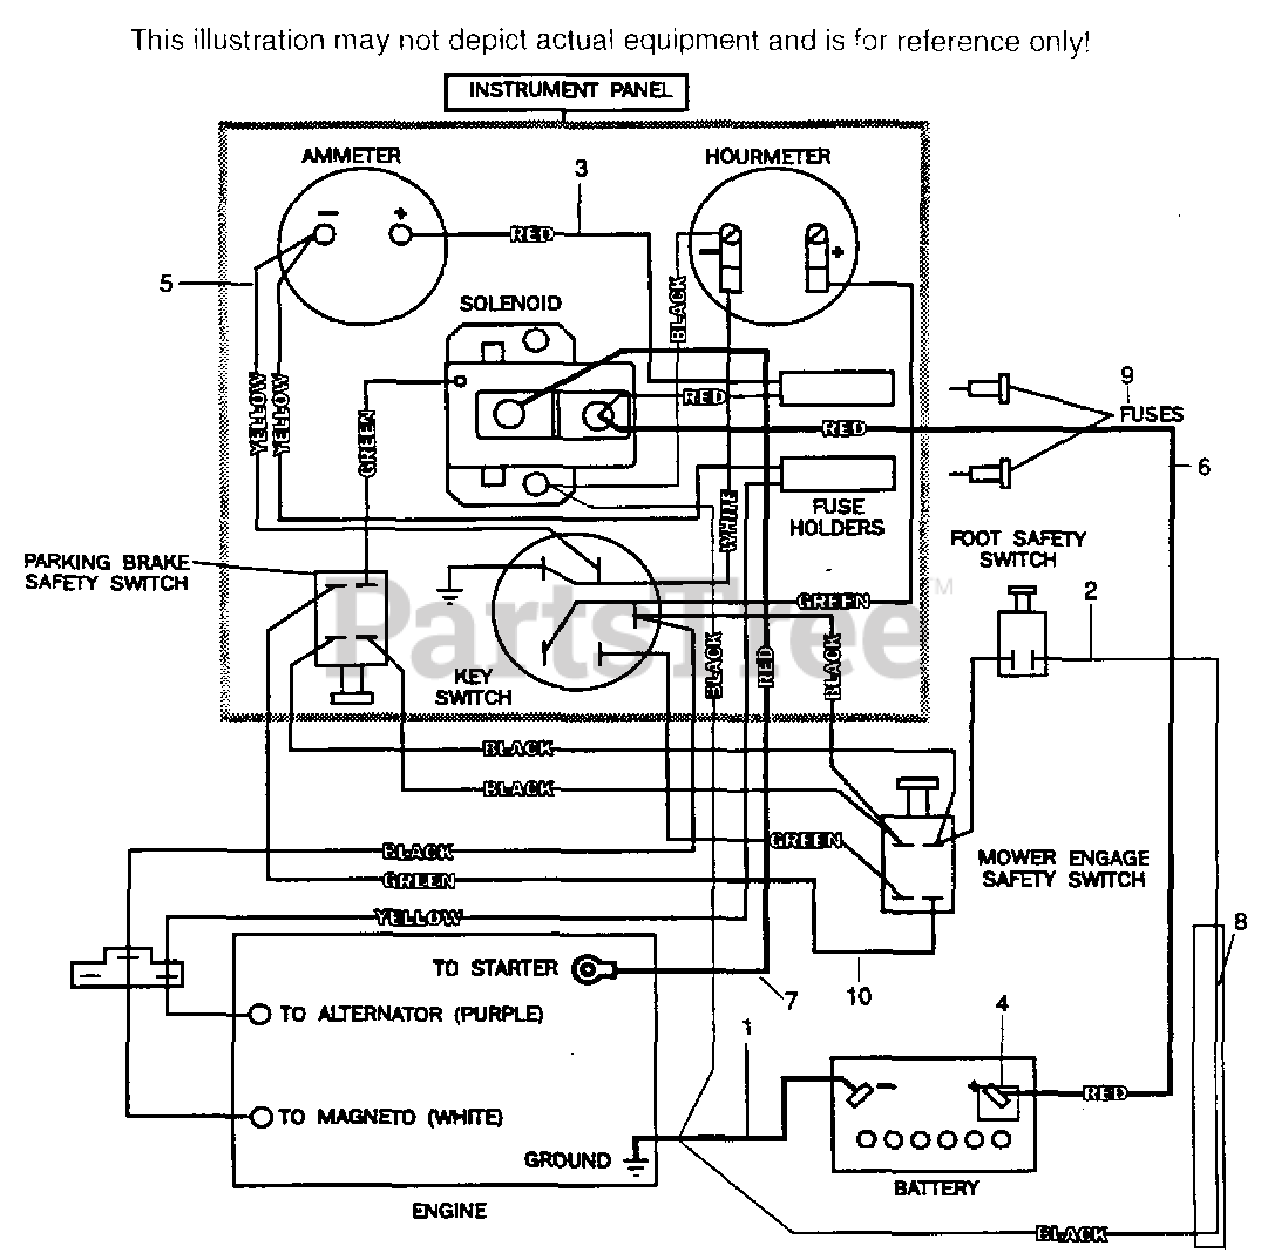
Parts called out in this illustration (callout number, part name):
1	BATTERY CABLE, GROUND
2	WIRE HARNESS, FOOT SAFETY SWITCH
3	WIRE HARNESS, SOLENOID TO AMMETER
4	RUBBER BOOT
5	WIRE HARNESS, INSTERMENT PANEL
6	BATTERY CABLE, LONG
7	BATTERY CABLE, SHORT
8	CONDUIT, BLACK NYLON
9	FUSE, 20 AMP BLADE TYPE AUTOMOTIVE
10	WIRE HARNESS, LOWER
